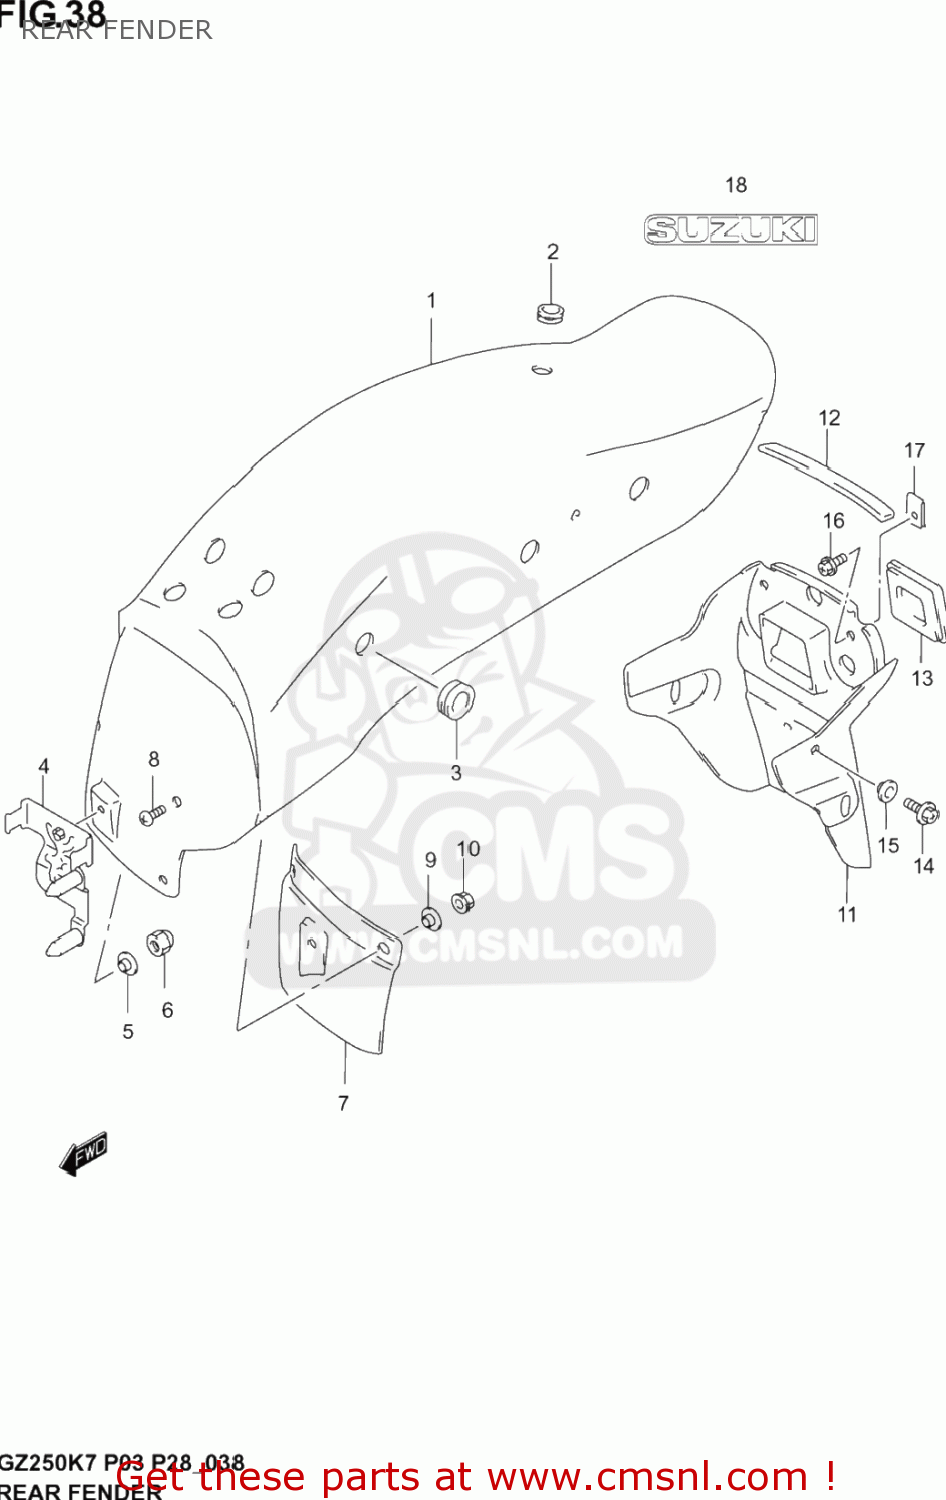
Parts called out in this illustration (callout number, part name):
1	FENDER,RR
2	CUSHION
3	CUSHION,RR FENDER
4	BRACKET,RR FENDER
5	WASHER
6	NUT
7	MUD GUARD, REAR FENDER
8	SCREW
9	WASHER
10	NUT
11	EXTENSION, REAR FENDER
12	CUSHION,RR FENDER EXTENSION
13	CAP,RR FENDER EXTENSION
14	BOLT
15	WASHER
16	SCREW
17	PLATE,FRAME COVER
18	EMBLEM "SUZUKI" (SILVER)
